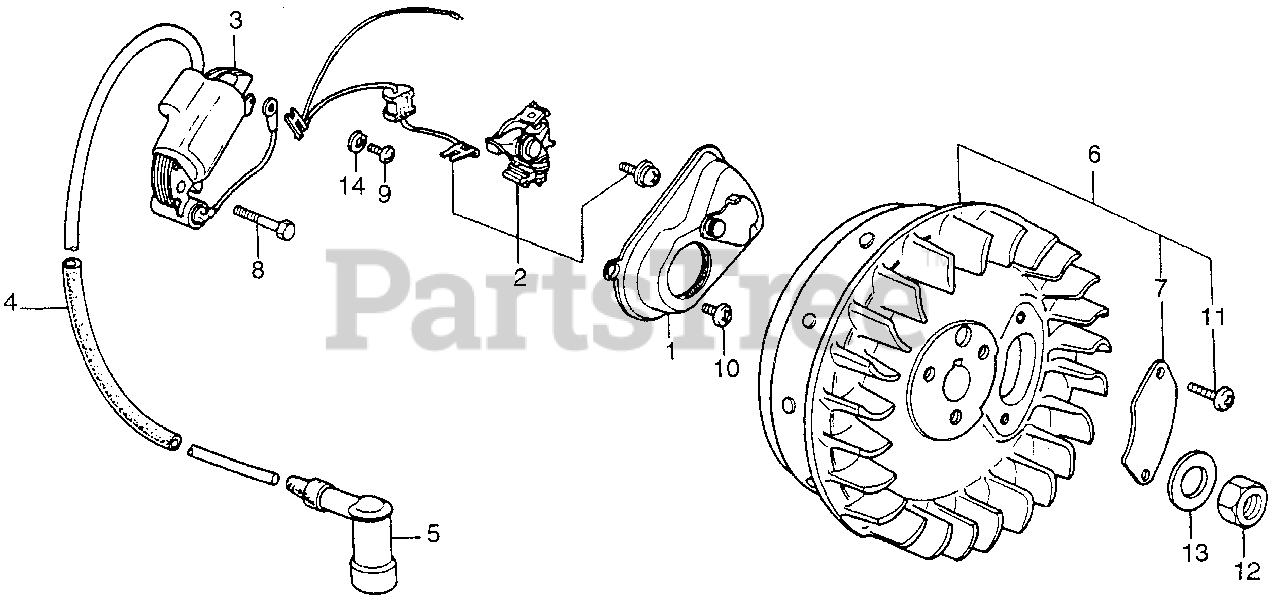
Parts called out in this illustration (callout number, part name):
1	COVER, POINT
2	POINTS ASSY.
3	COIL, IGNITION
4	TUBE, IGNITION RUBBER
5	TERMINAL ASSY., IGNITION
8	BOLT, HEX. (6X28)
9	SCREW, PAN (3X6) (NOT AVAILABLE)
10	SCREW, PAN (5X6)
14	WASHER, SPRING (3MM)
